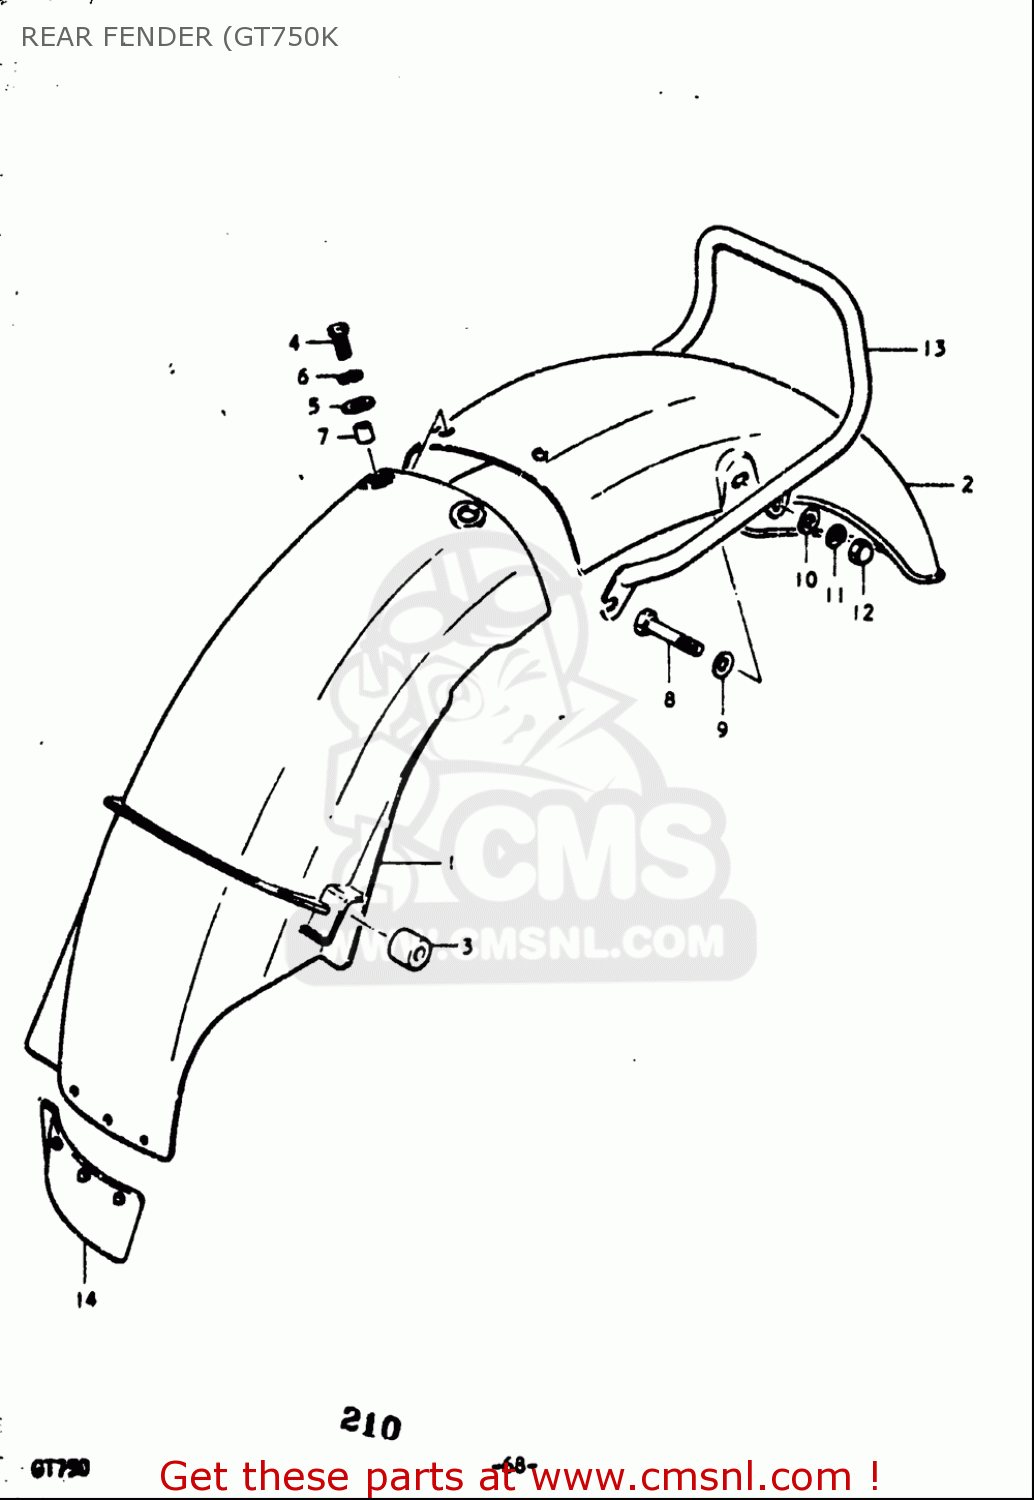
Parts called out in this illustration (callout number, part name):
1	BODY,RR FENDER FR
3	CUSHION
4	BOLT
5	WASHER
6	WASHER,LOCK
7	SPACER
8	BOLT
9	WASHER(8.5X20X2.6)
10	WASHER
11	WASHER,LOCK
12	NUT
14	GUIDE,RR FENDER MUD
